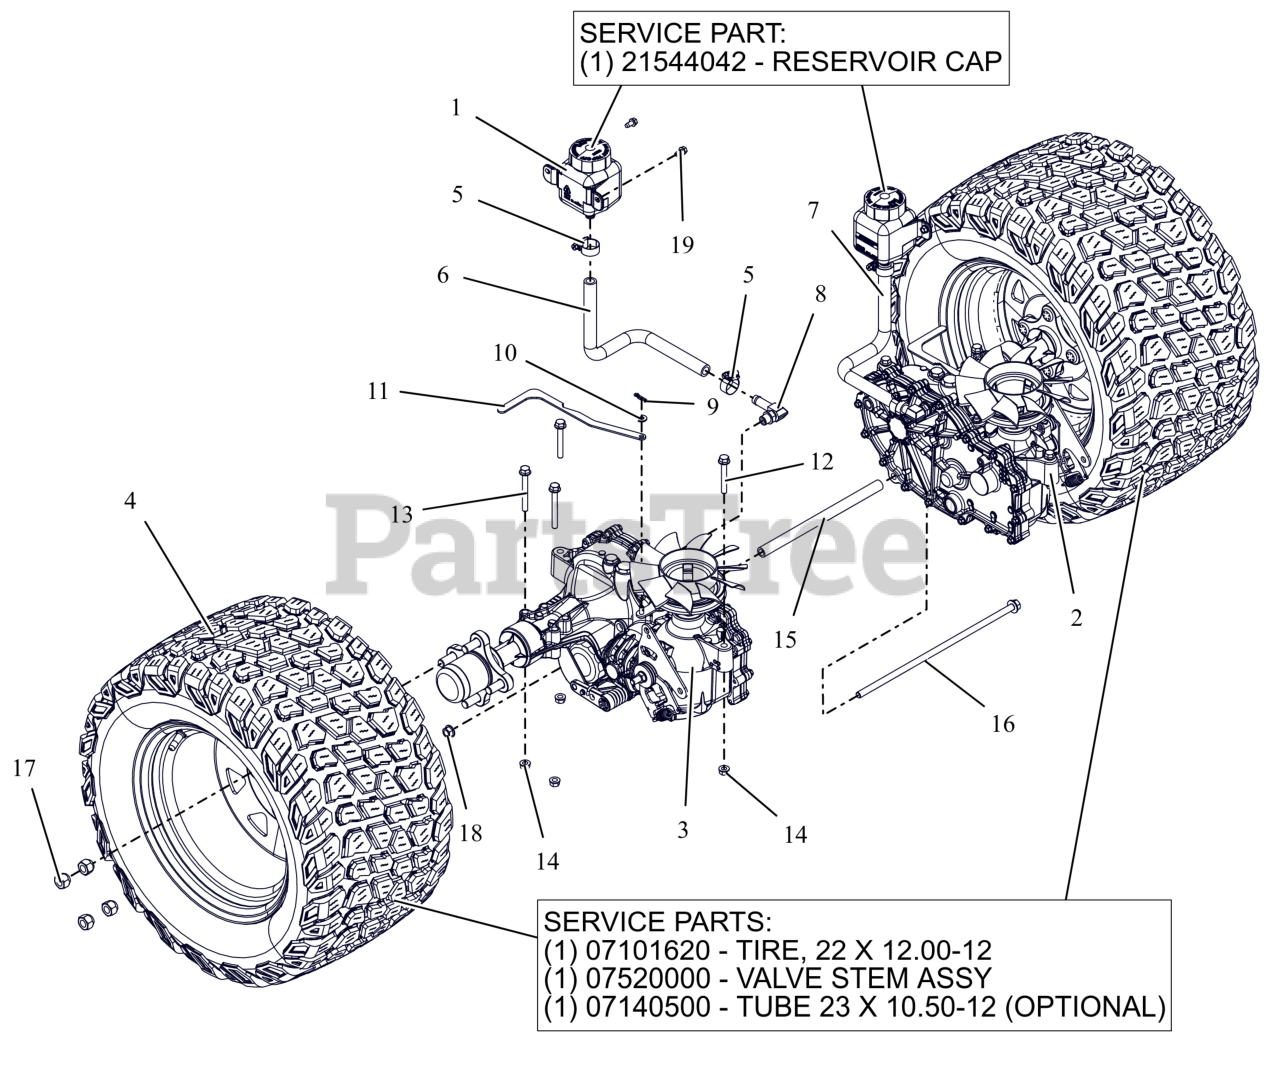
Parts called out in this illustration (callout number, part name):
1	TANK, EXPANSION
1	CAP, HYDRO RESERVOIR REPLAC.
2	TRANSAXLE, ZT3100 - LH
3	TRANSAXLE, ZT3100 - RH
4	ASM-WHL/TIRE 22X12-12 XT TREAD
4	TIRE, 22X12-12
4	VALVE STEM ASS'Y
4	TIRE TUBE 22,23,24/8.50/9.50/10.00/10.50/12.00-12 4 PLY TR13 STRAIGHT VALVE
5	CLAMP,.88 DIA. HOSE
6	HOSE, FORMED EXPANSION -HD RH
7	HOSE, FORMED EXPANSION -HD LH
8	FITTING, HYD (90 DEG)
9	PIN, HAIR #225 .072X1.09
10	WSHR,FLT .281X.625X.065 ZCC
11	BRKT, VALVE DUMP
12	BLT,HEX-FLG .31-18X2.25 G5 ZCC
13	BLT,HEX-FLG .31-18X2.75 G5 ZCC
14	NUT,LK-CTR-FLG .31-18 GF ZCC
15	SPCR,TRANS. .406IDX.63ODX9.95L
16	BLT,HEX-FLG .38-16X13 G5 ZCC
17	NUT, WHEEL .50-20 ZCC
18	NUT-LK-TOP-FLG .38-16 ZC120
19	SCR-TAP .25-20X.50 HWH ZCC
